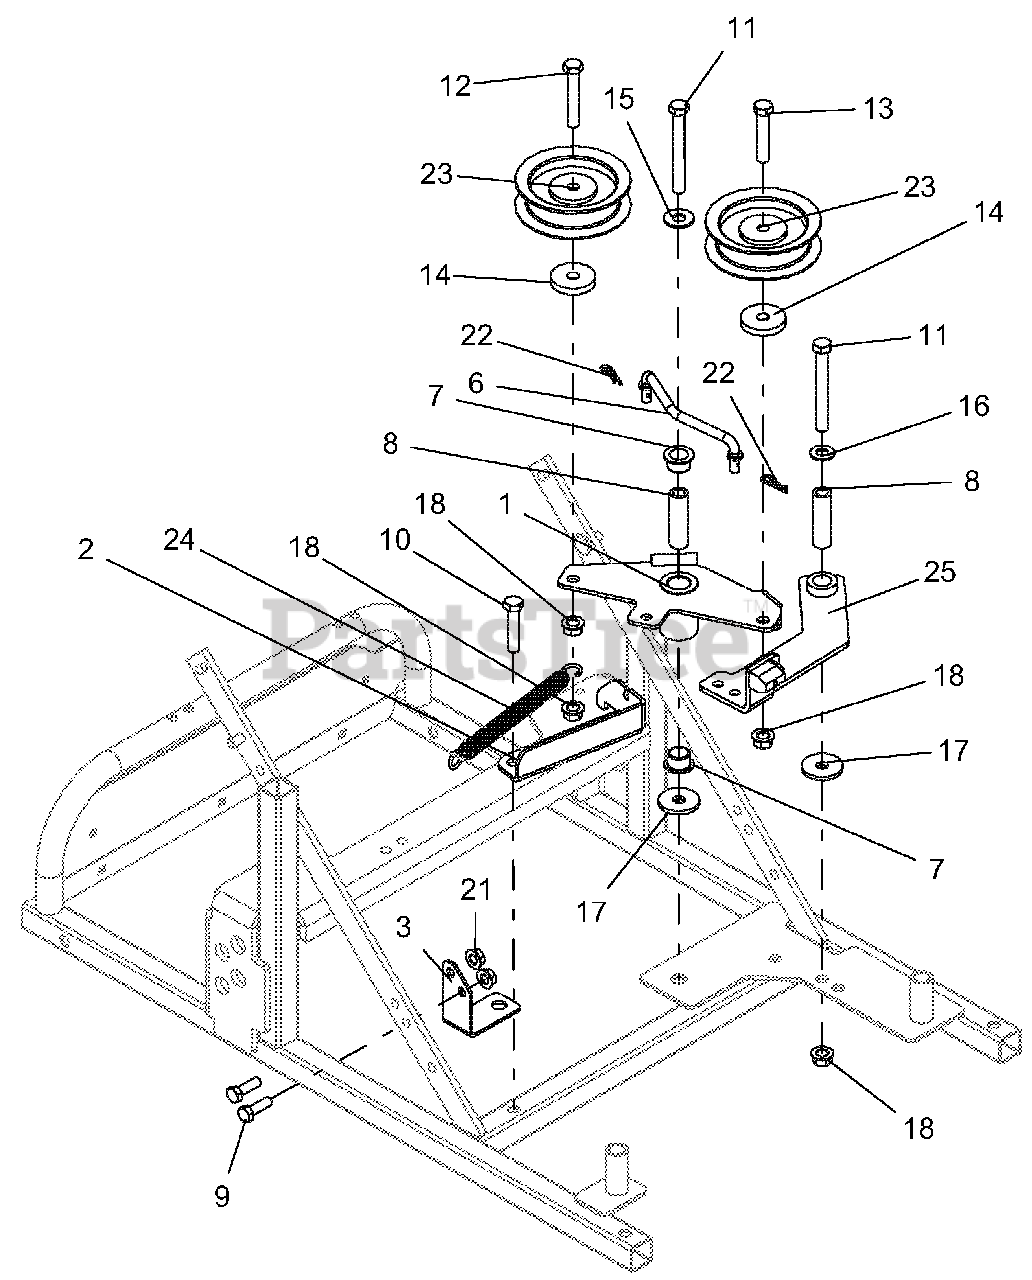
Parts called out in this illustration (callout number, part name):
1	WMT, IDLER ROCKER TM-26 (BLACK)
2	MOUNT, LOWER PTO CABLE (BLACK)
3	MOUNT, HWM PTO IDLER SPRING (BLACK)
6	ROD, SPINDLE BRAKE
7	BSHG, FLANGE .625 x .75 x .50 x 1.00
8	BSHG-SLV .375X.625X2.03
9	BLT-HEX .31-18X1.00 GR5 YWZC
10	BLT-HEX .38-16X1.75 GR5 YWZC
11	BLT-HEX .38-16X3.25 GR5 YWZC
12	BLT-HEX .38-16X2.25 GR5 YWZC
13	BLT-HEX .38-16X2.00 GR5 YWZC
14	WSHR-FL-STL .406X1.50X.245 YWZC
15	WSHR-FL-STL.438X1.00X.083 YWZC
16	WSHR-FL-STL.406X.812X.065 YWZ
17	WSHR-FL-STL .406X1.375X.135 YZ
18	NUT, LK-TOP-FLG .38-16 YWZC
21	NUT, LK-TOP-FLG .312-18 YWZC
22	PIN, HAIR INT .08X.18X1.18 YWZC
23	FLAT IDLER, STENS 280-671
24	SPRG, EXTENSION
25	KIT, BRAKE ARM ASSY, HWM
